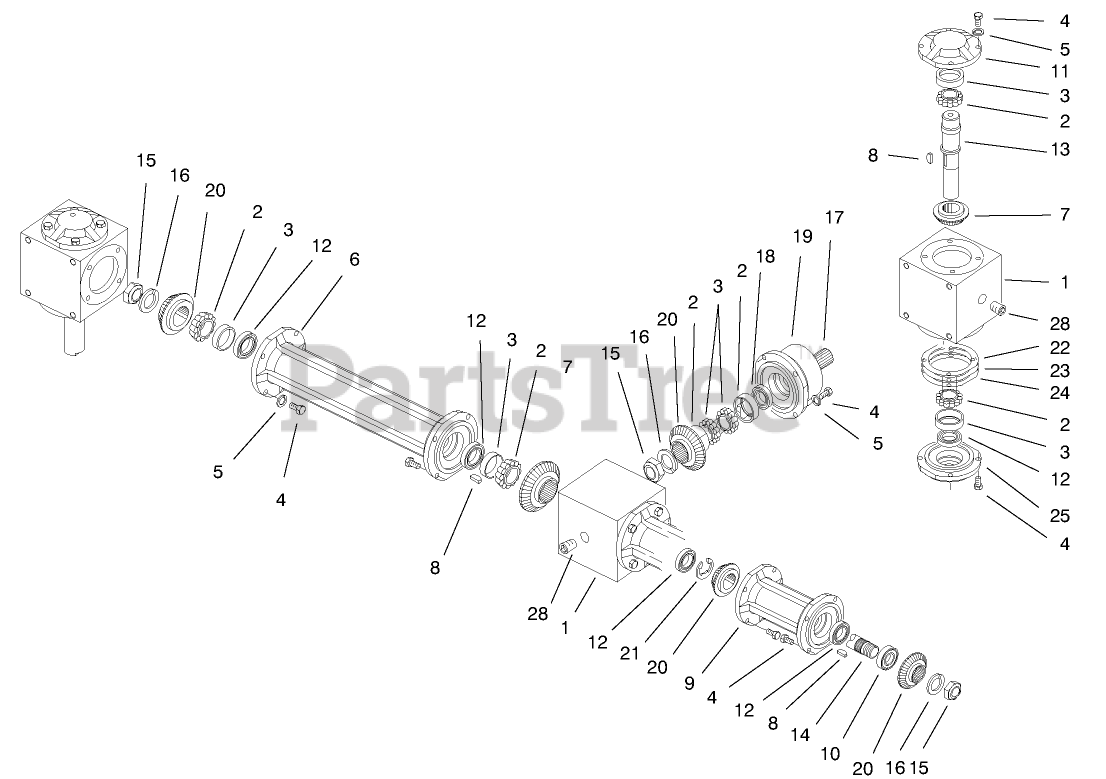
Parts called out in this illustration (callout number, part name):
1	HOUSING
2	BEARING - CONE
3	Cup
4	SCREW - HH
5	WASHER - LOCK
6	Connector-Hub
7	Gear-RH
9	Connector-Hub
10	BEARING - BALL
11	CAP - BLANK
12	Seal
13	Shaft-Thru
14	SHAFT
15	NUT - LOCK
16	WASHER - LOCK
17	SHAFT - HUB
20	PINION - LH
21	RING - RETAINING
22	Gasket-.015
23	Gasket-.005
24	GASKET - .003
25	CAP - THRU
28	PLUG (OBS, C/R TO 281-10)
